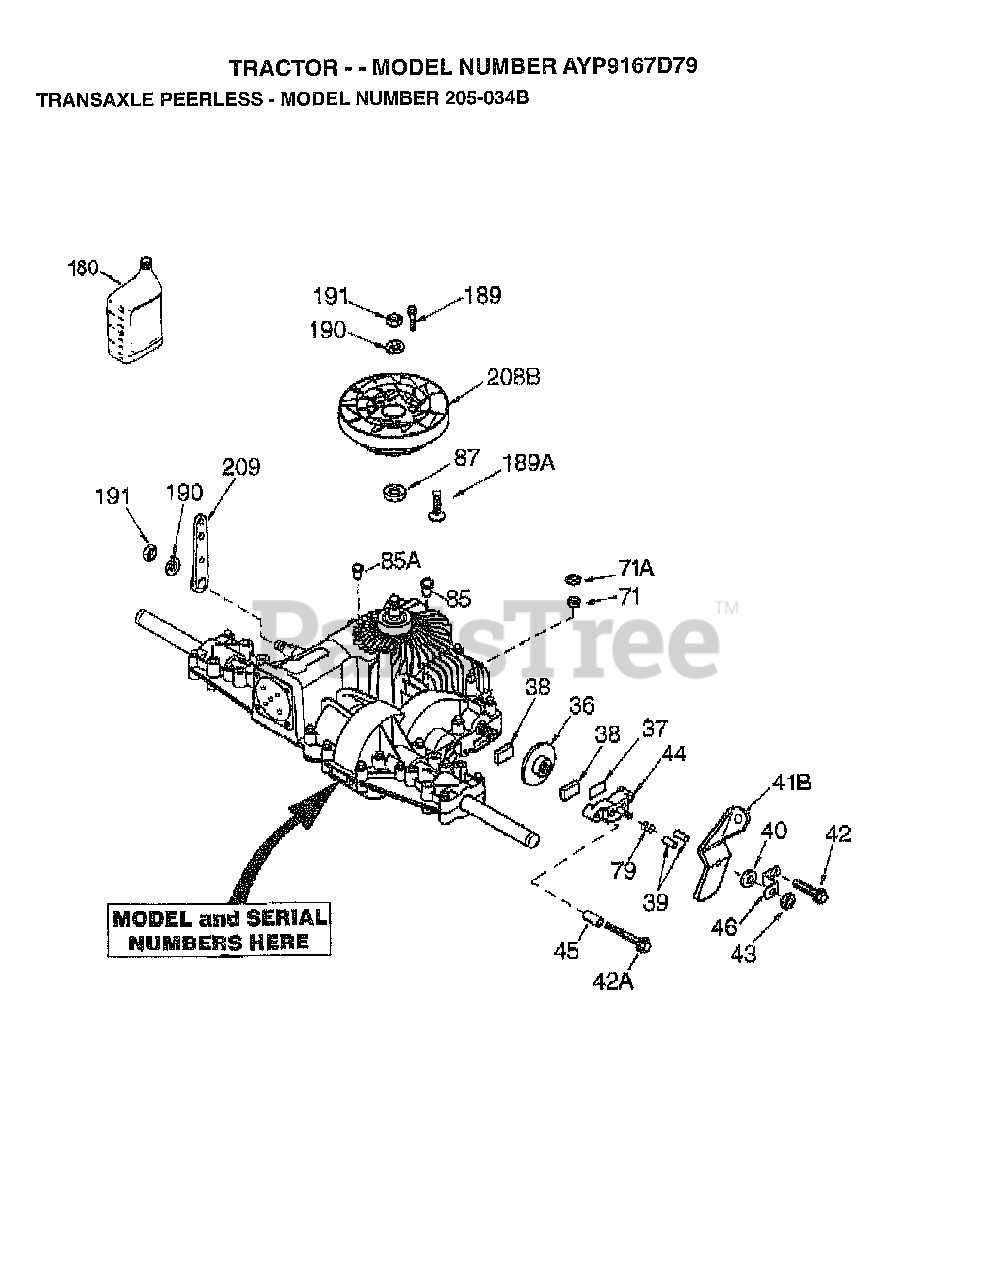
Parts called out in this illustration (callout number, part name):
37	PLATE BRAKE PAD
41B	BRAKE LEVER
42A	SCREW, 1/4-20 X 2-1/4
43	LOCKNUT 5/16-24
44	HOLDER BRAKE PAD
46	BRAKE LEVER BRACKET
71	SEAL SQUARE CUT
85	OIL FILL PLUG
85A	TUBE PLUG, 3/8"
180	GEAR OIL 80W90
189	DRIVE SCREW
208	FAN/COUPLING
